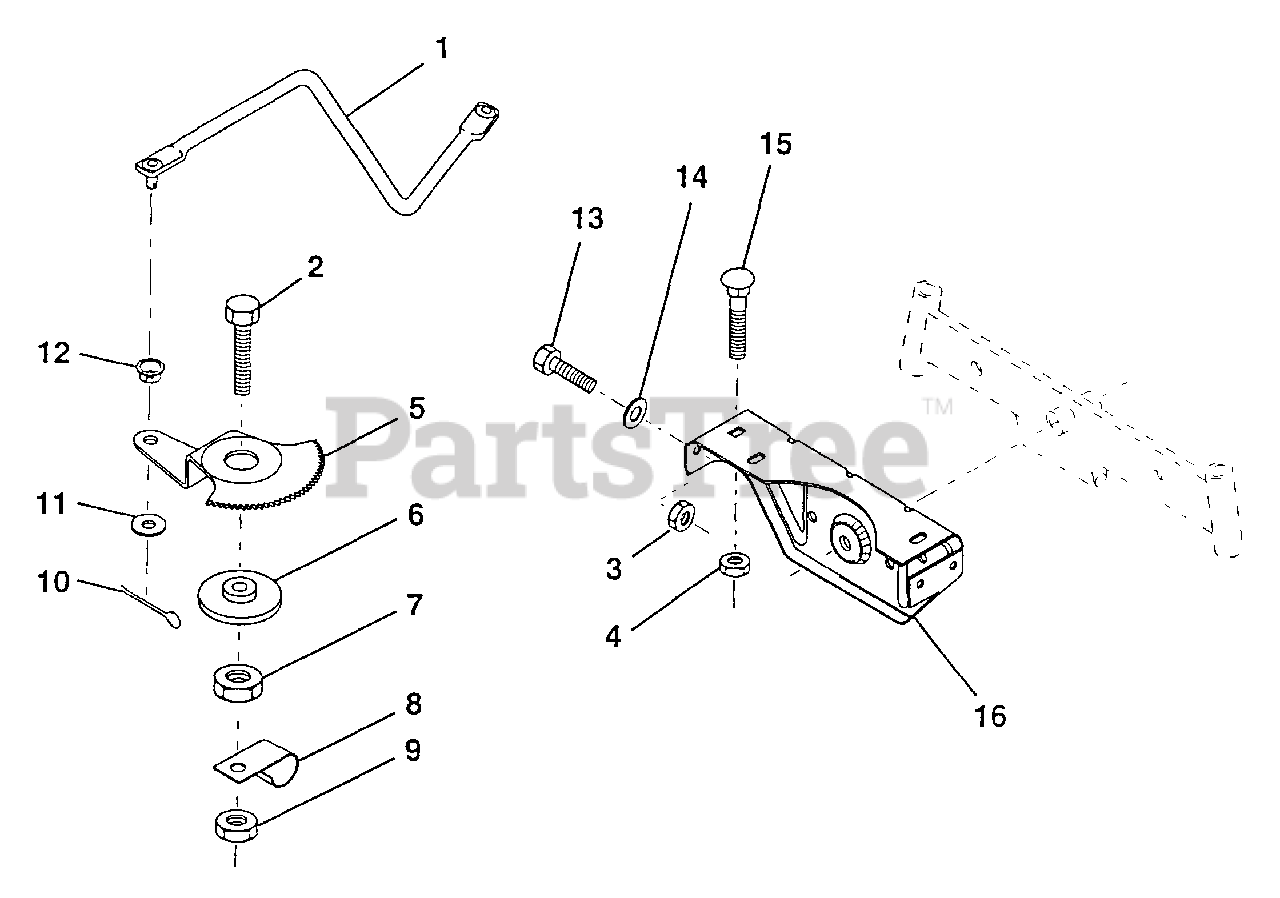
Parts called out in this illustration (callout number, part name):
1	Link, Drag
2	Bolt, Fin Hex 1/2-13 x 1-3/4
3	Nut, Crownlock 5/16-18
4	Nut, Crownlock 3/8-16
5	Gear, Sector
6	Bushing
7	Nut, Heavy Hex Top Lock 1/2-13 UNC (AYP part number)
8	Clip, Insulated
9	Nut, Crownlock 3/8-16
10	Pin, Cotter 1/8 x 3/4
11	Washer, 13/32 x 13/16 x 16 Ga.
12	Bushing
13	Bolt, Hex Hd. 5/16-18 UNC x 3/4
14	Washer 11/32 x 7/8 x 16 Ga.
15	Bolt, Carriage 3/8-16 UNC x 3/4
16	Support, Front Axle
